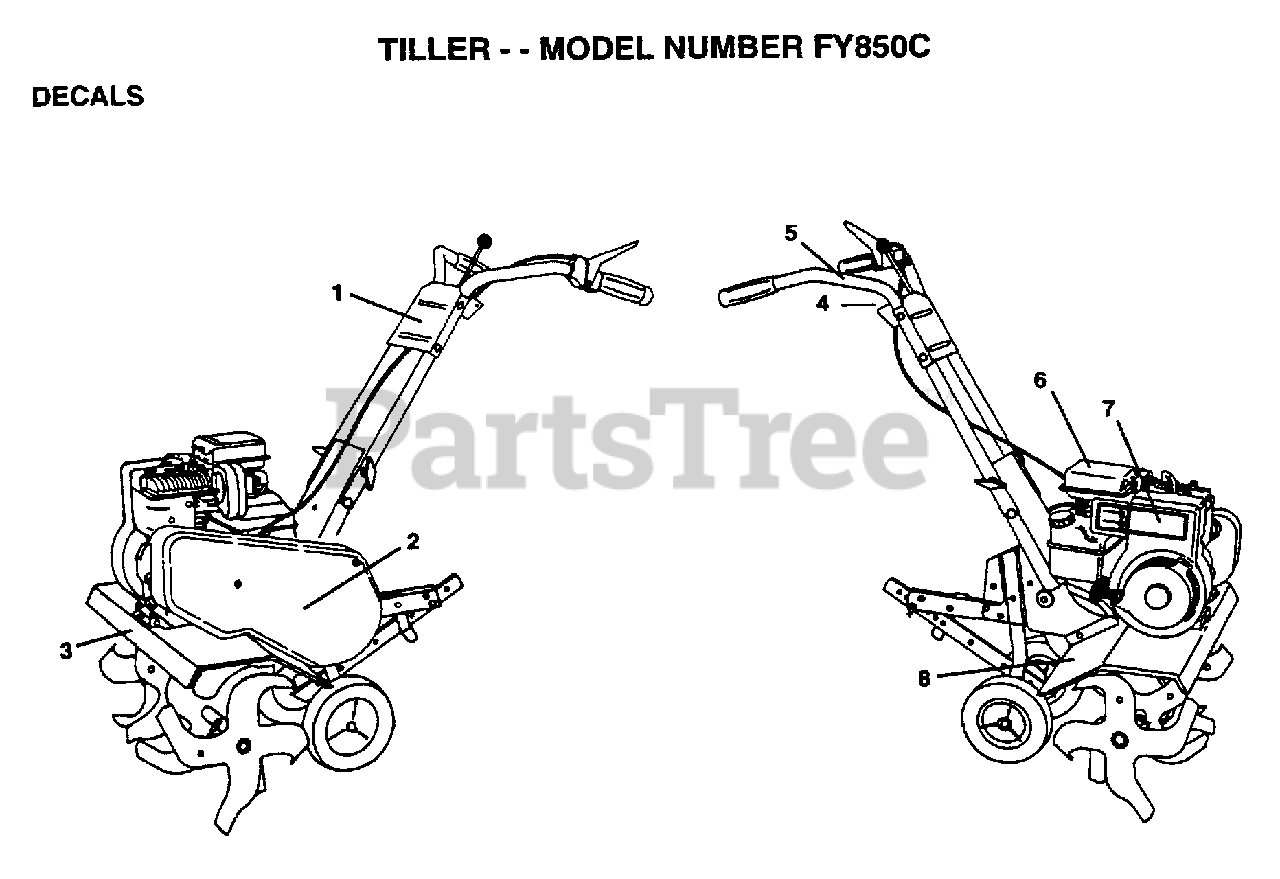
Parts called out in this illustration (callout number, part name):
1	DECAL HANDLE BRKT
2	DECAL.BELT.GUAR
3	DECAL TINE SHIELD
4	DECAL REVERSE
5	DECAL TI
6	DECAL TI
7	DECAL, BRIGGS & STRATTON
